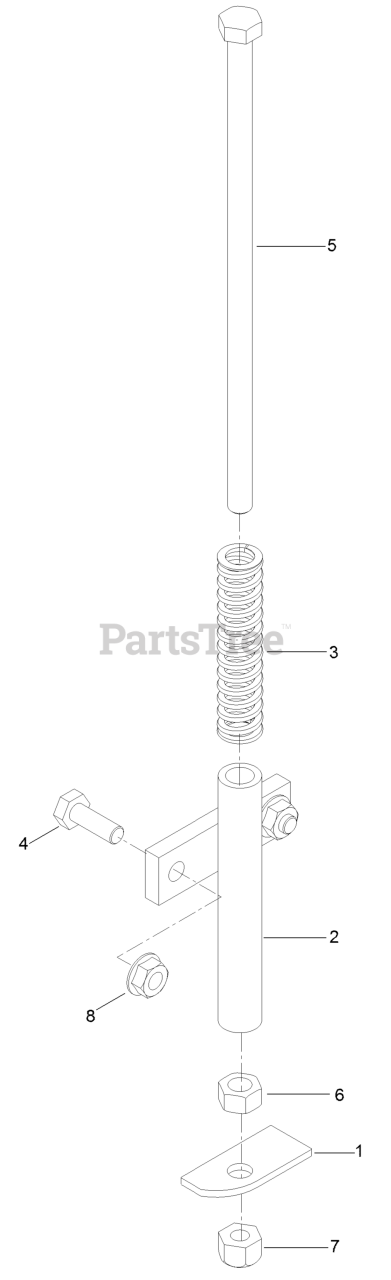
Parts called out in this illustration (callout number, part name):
1	Plate-Switch
2	MOUNT-SPRING, SEAT
3	SPRING-SWITCH, SEAT
4	SCREW-HH
5	SCREW-HH
6	NUT-HEX
7	NUT-LOCK, NI
